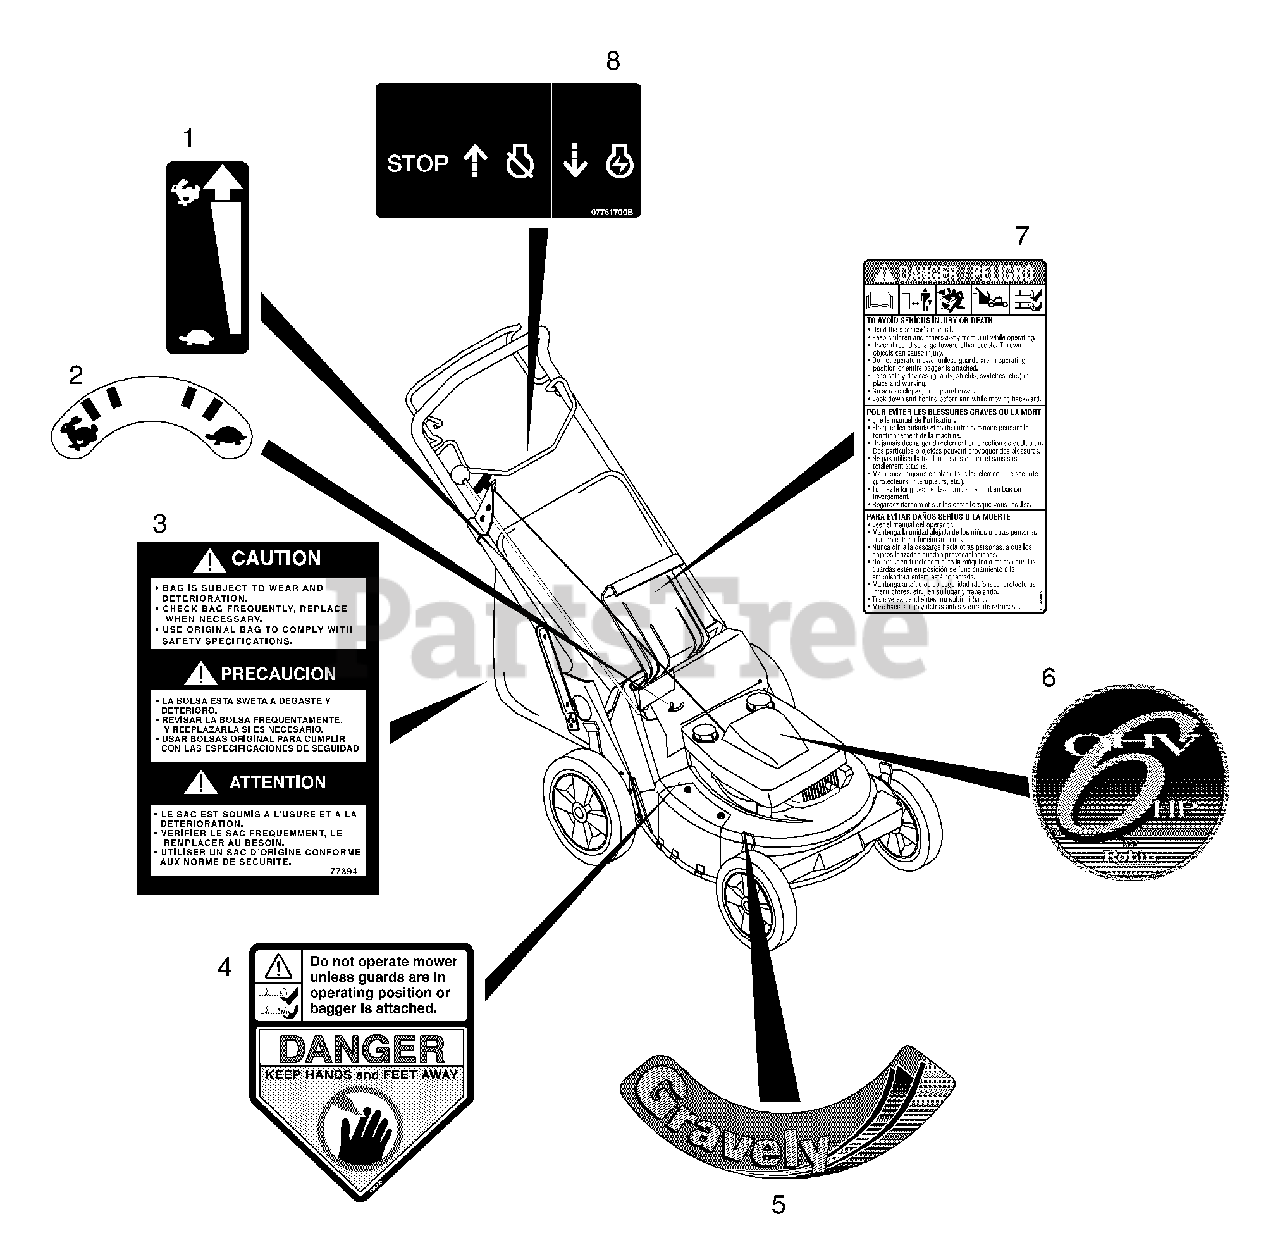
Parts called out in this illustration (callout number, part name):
1	Decal, Speed Control
2	Decal, Traction Speed
3	Decal, Bagger-21"
4	Decal, CPSC Danger
5	Decal, Commercial
6	Decal, OHV6 Robin
7	Decal, Bilingual Danger
8	Decal, Engine Control
